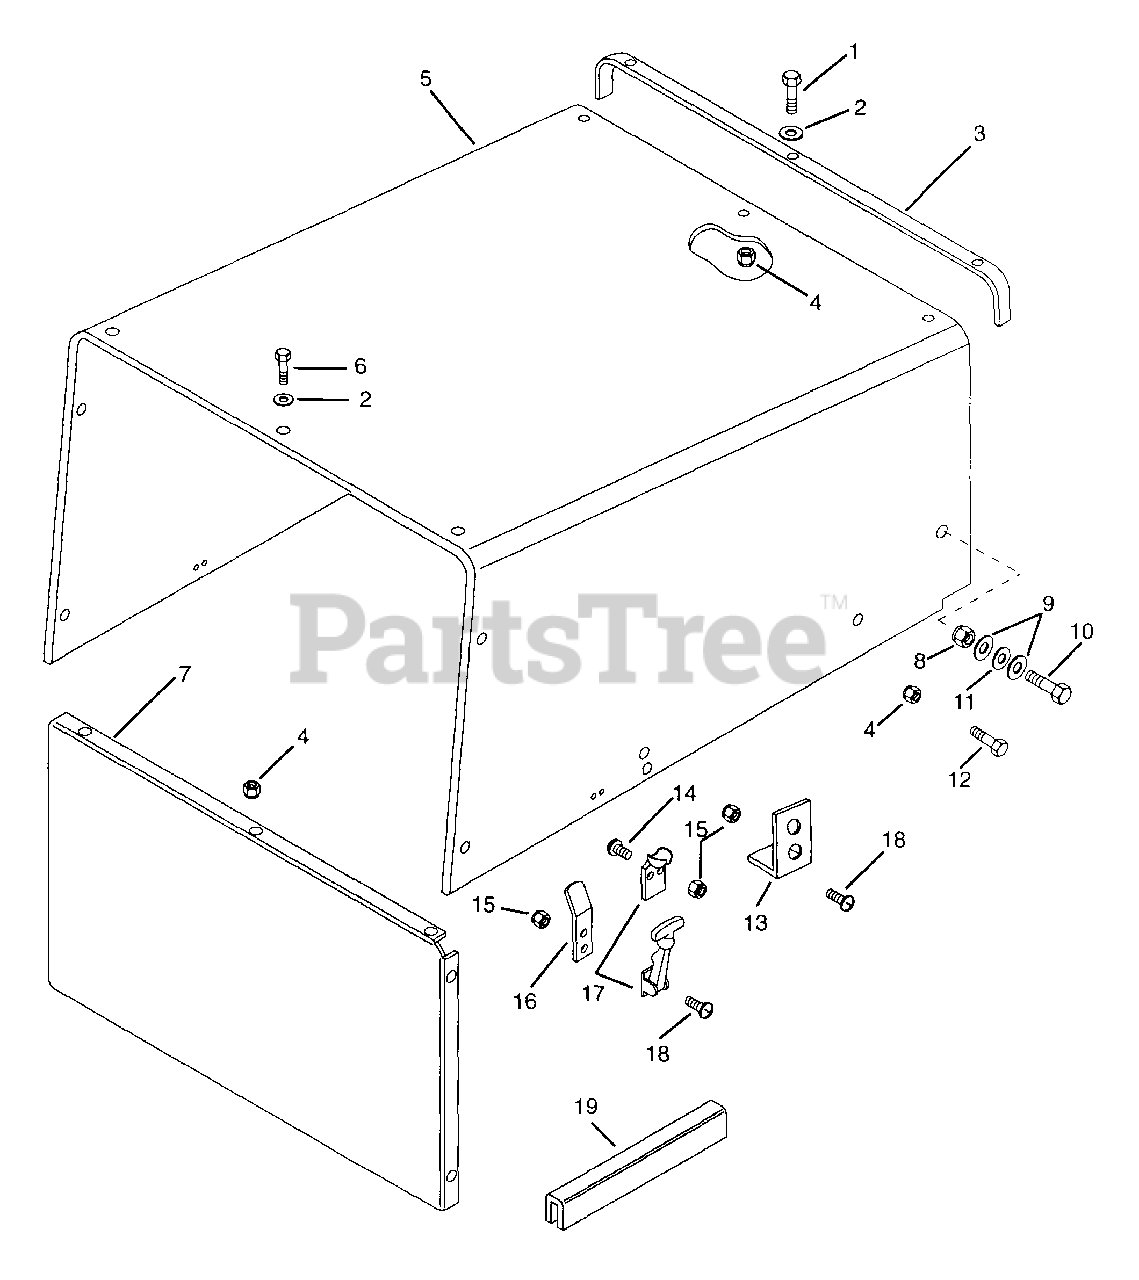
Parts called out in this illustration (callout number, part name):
1	Bolt-Hex .25-20 x .75 Grade 5
2	Washer-Flat-Steel .281 x .625 x .065
3	Brace, Hood
4	Nut-Locking-Nylon .250-20 Grade 2
5	Hood, Engine
6	Bolt-Hex .25-20 x .63
7	Panel, Hood
8	Nut-Locking-Nylon .375-16 Grade 2
9	Washer-Flat-Steel .406 x .812 x .065
10	Bolt-Hex .380-16 x .875
11	Washer-Flat-Steel .505 x .880 x .072
12	Bolt-Hex .25-20 x .875
13	Bracket (989300,301)
14	Screw-Machine 10-24 x .50
15	Nut-Locking 10-24
16	Plate, Guide
17	Latch
18	Screw-Machine 10-24 x .750
19	Strip, Cowl
